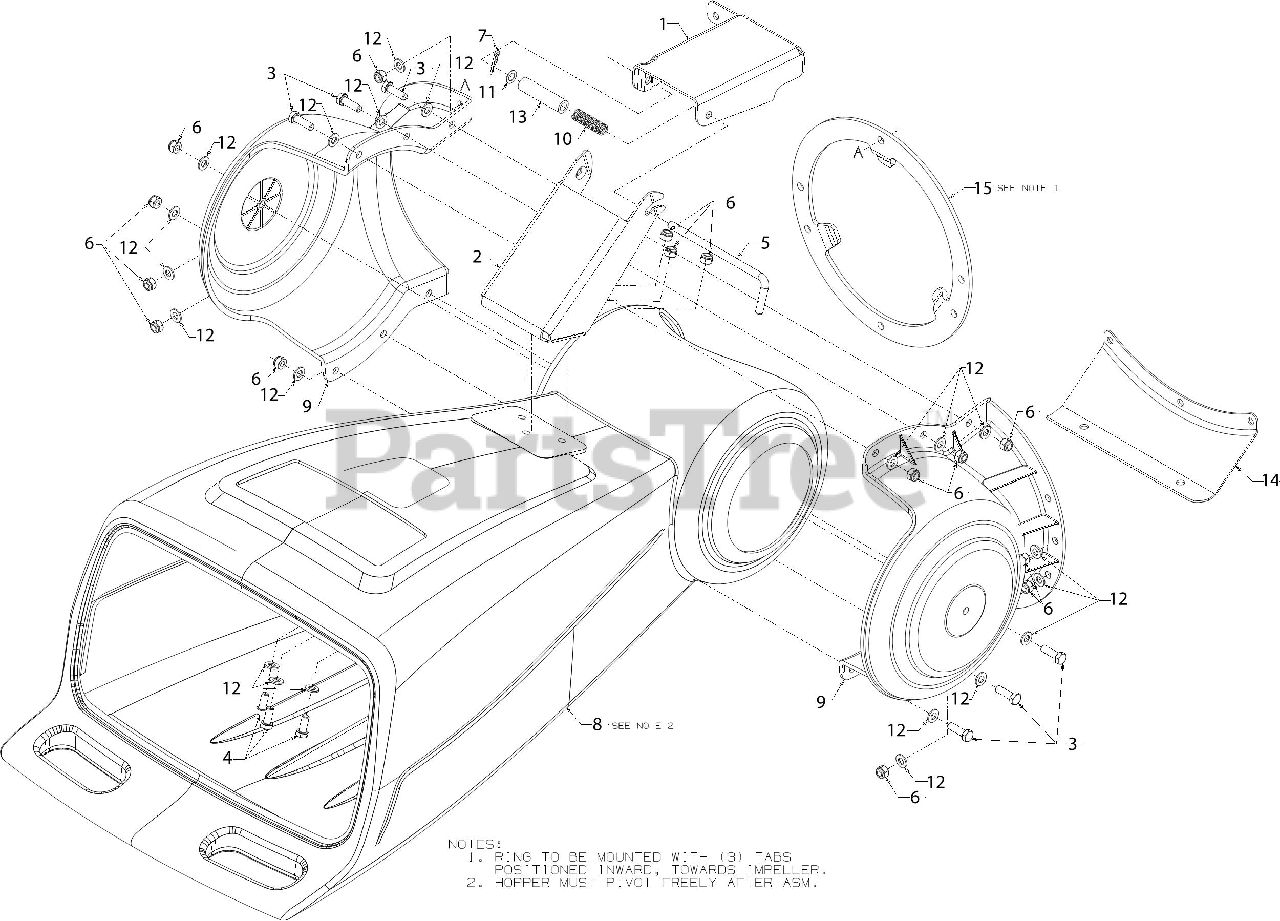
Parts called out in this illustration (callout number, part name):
1	HOPPER BRACKET ASSEMBLY
2	HOPPER BRACKET ASSEMBLY
3	SCREW 5/16-18 x 1.0 GR5
4	SCREW 5/16-18 x .75 GR5
5	LOCK ROD
6	HEX NUT
7	COTTER PIN .072 DIA
8	SHREDDER HOPPER
9	CHIPPER SHREDDER HOPPER COLLAR
10	COMPRESSION SPRING
11	FLAT WASHER
12	FLAT WASHER
13	SPACER-.375 x 2.50
14	FRONT SUPPORT BRACKET
15	HOPPER BACK-UP PLATE
